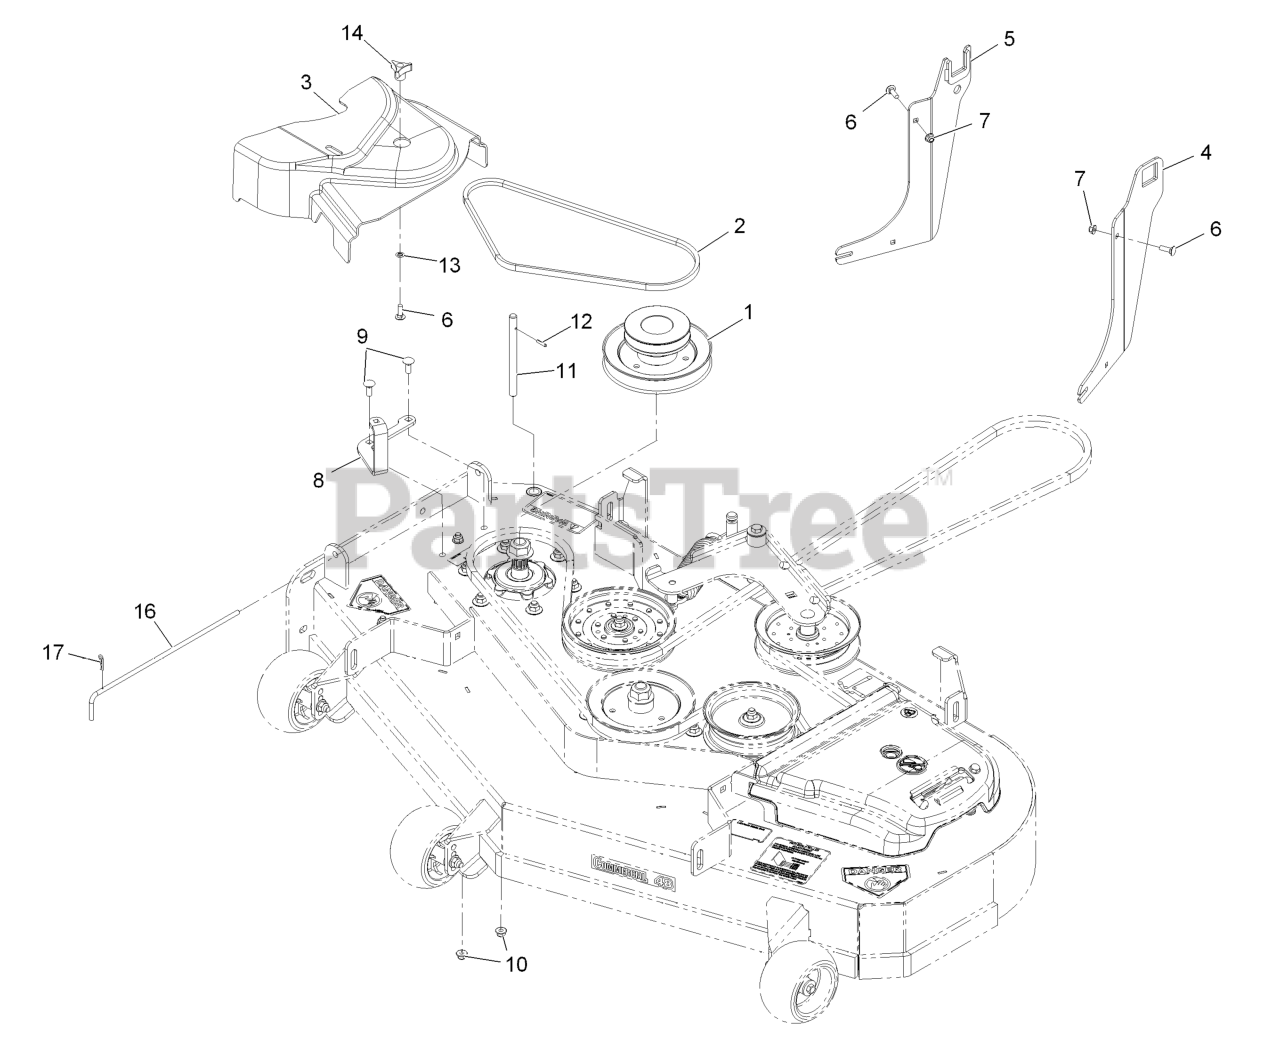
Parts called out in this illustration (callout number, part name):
1	JACKSHAFT-UV DRIVE 48 SPL
2	BELT-UV E 48
3	COVER-BELT, UV 48
4	BRACKET ASM, LH
5	BRACKET ASM, RH
6	BOLT-CARR
7	NUT-HF, NI
9	BOLT-CARR
10	NUT-HF, NI
11	SHAFT-CATCHER, GRASS
12	PIN-ROLL
13	RING-RETAINING, BOLT
14	KNOB-3 PRONG
16	PIN,CHUTE PIVOT
17	PIN-COTTER
